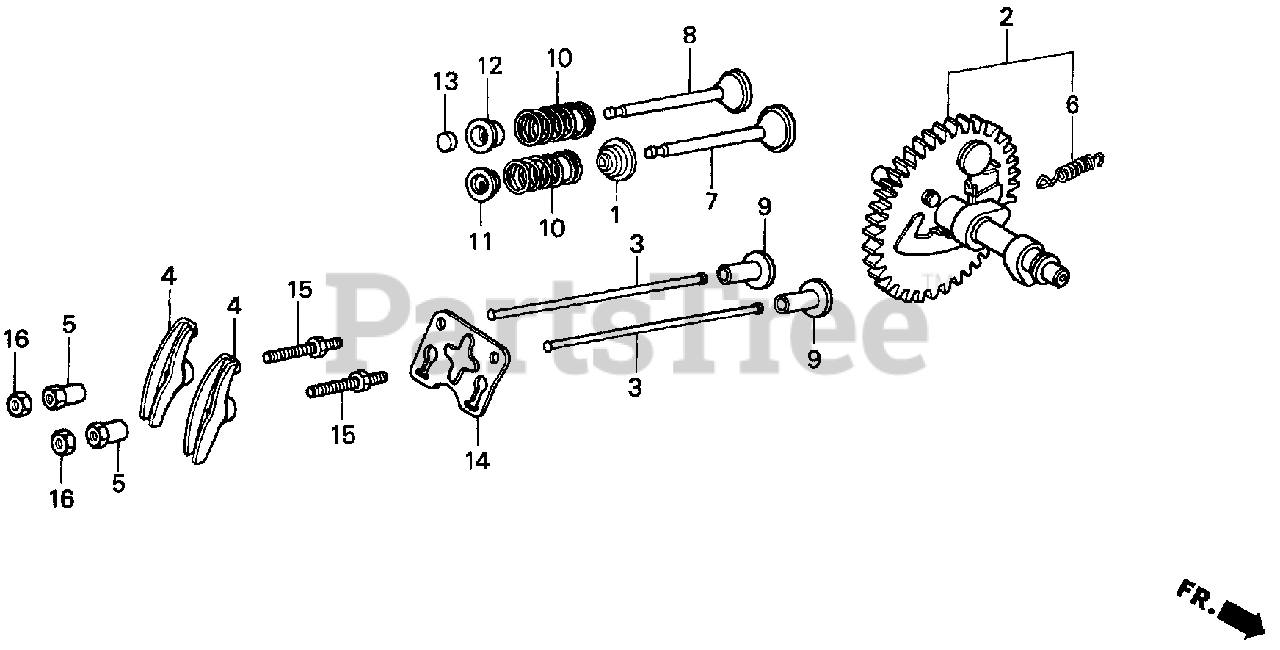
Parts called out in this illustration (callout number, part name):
1	SEAL, VALVE STEM
2	CAMSHAFT ASSY.
3	ROD, PUSH
4	ARM, VALVE ROCKER
5	PIVOT, ROCKER ARM
6	SPRING, WEIGHT RETURN
7	VALVE, IN.
8	VALVE, EX.
9	LIFTER, VALVE
10	SPRING, VALVE
11	RETAINER, IN. VALVE SPRING
12	RETAINER, EX. VALVE SPRING
13	ROTATOR, VALVE
14	PLATE, PUSH ROD GUIDE
15	BOLT, PIVOT (8MM)
16	NUT, PIVOT ADJ.
